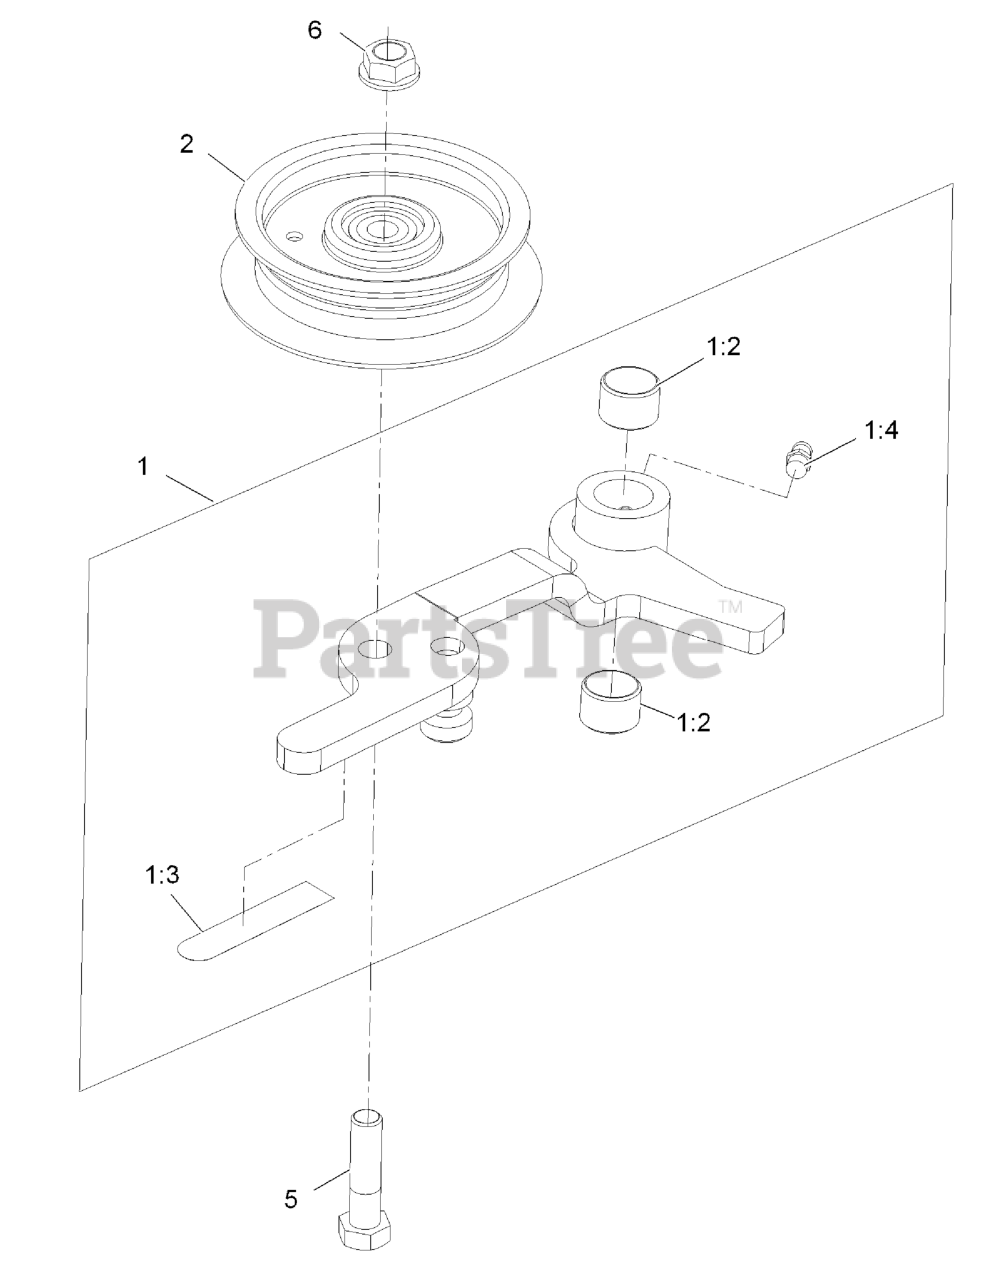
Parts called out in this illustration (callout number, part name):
1	ASM, IDLER ARM - SERVICE
1:2	BUSHING
1:3	DECAL-WARNING
1:4	FITTING-GREASE
2	IDLER-FLAT
5	SCREW-HH
6	NUT-HHF, WHIZ
